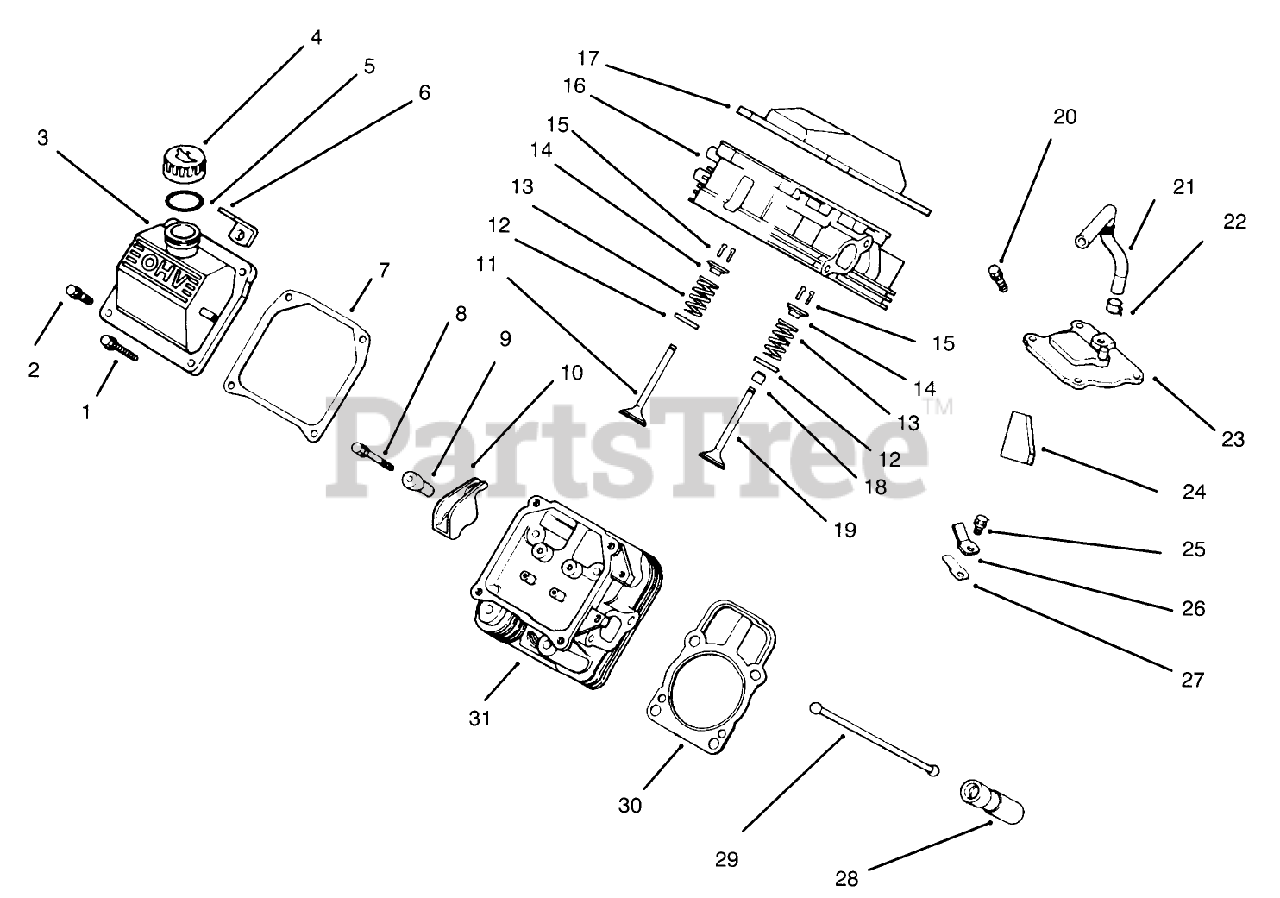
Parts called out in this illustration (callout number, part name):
1	Screw
3	Cove-Rocker
4	Cap-Oil Fill Tube
5	ORing
6	Strap-Lifting
7	Gasket-Valve Cover
9	Ball-Rocker Pivot
10	Arm-Rocker
11	Valve-Exhaust
12	Retainer-Spring
13	Spring-Valve
14	Cap-Valve Spring
15	Kit-Retainer
16	Head Assembly #1 Cylinder
17	Cover-Rocker
18	Seal
19	Valve-Intake
21	Hose-Breather
22	Clamp
23	Kit,-Breather
24	Filter-Breather
26	Retainer-Reed
28	Lifter-Valve
29	Rod-Push
30	Gasket-Cylinder Head
31	Head Assembly #2 Cylinder
